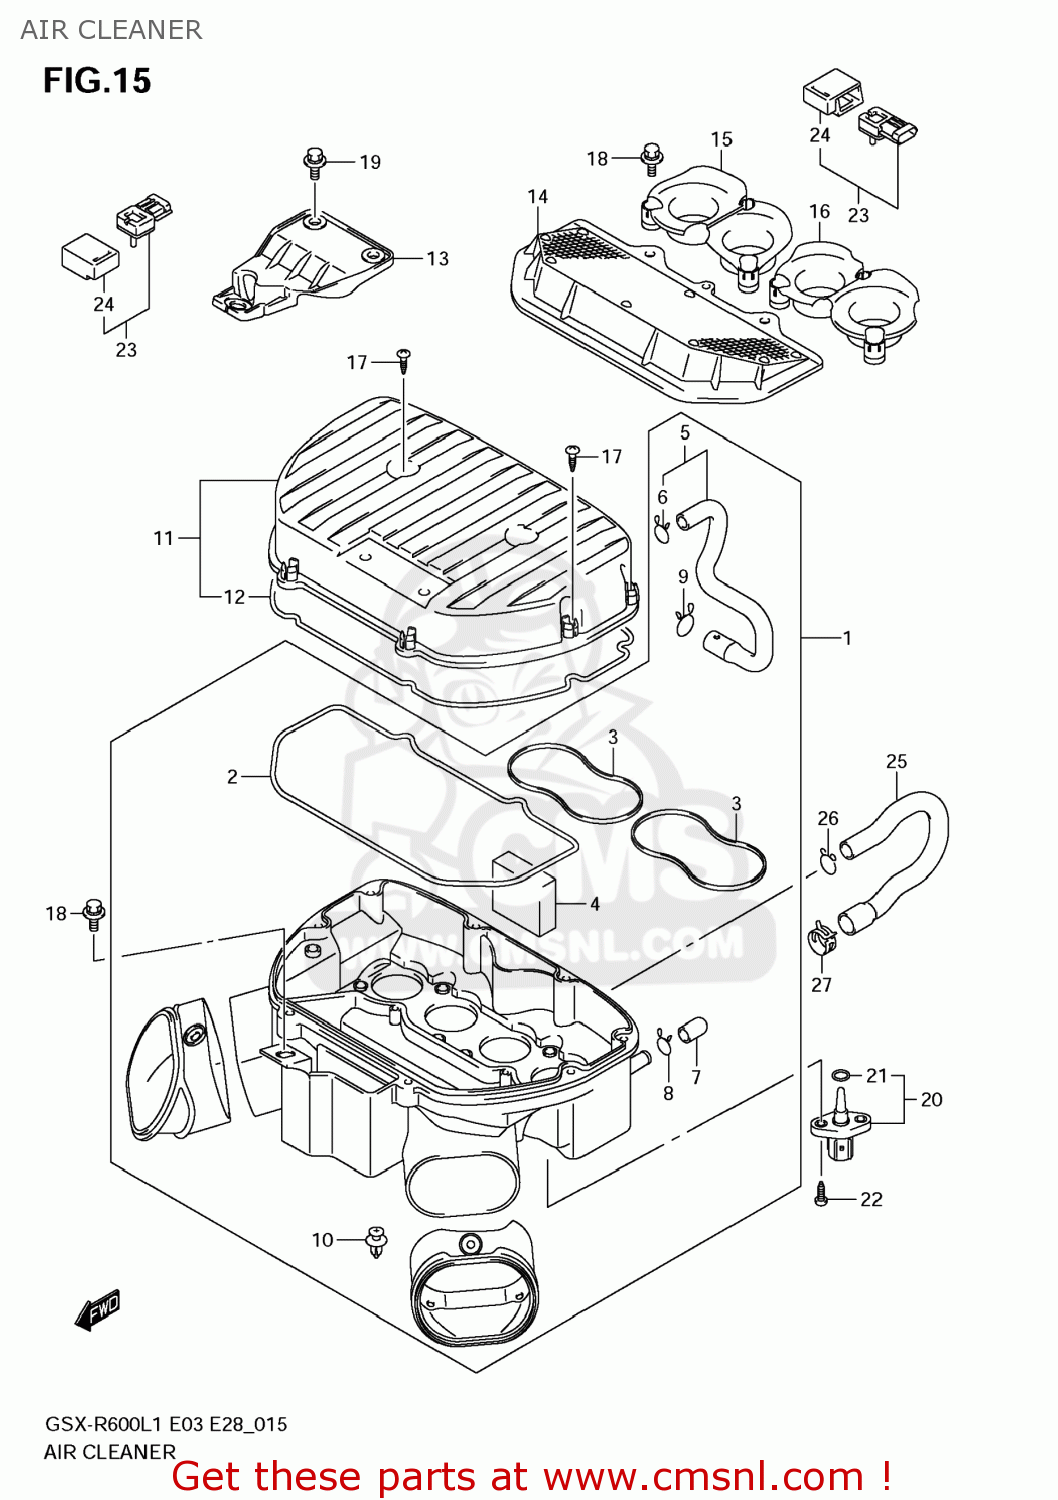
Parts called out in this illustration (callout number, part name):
1	CASE,AIR CLEANER
2	GASKET,CASE (NAS)
3	GASKET,CASE (NAS)
4	FILTER,BREATHER
5	TUBE,BREATHER
6	CLIP
7	PLUG
8	CLIP
9	CLIP
10	CLIP(BLACK)
11	CAP,AIR CLEANER
12	GASKET,CAP (NAS)
13	HOLDER,AIR CLEANER
14	FILTER ASSY
15	FUNNEL,OUTLET,R
16	FUNNEL,OUTLET,L
17	SCREW
18	BOLT,AIR CLEANER CASE
19	BOLT(6X16)
20	SENSOR,AIR TEM
21	O RING
22	SCREW
23	SENSOR,AIR PRESSURE
24	COVER
25	HOSE
26	CLIP
27	CLIP
